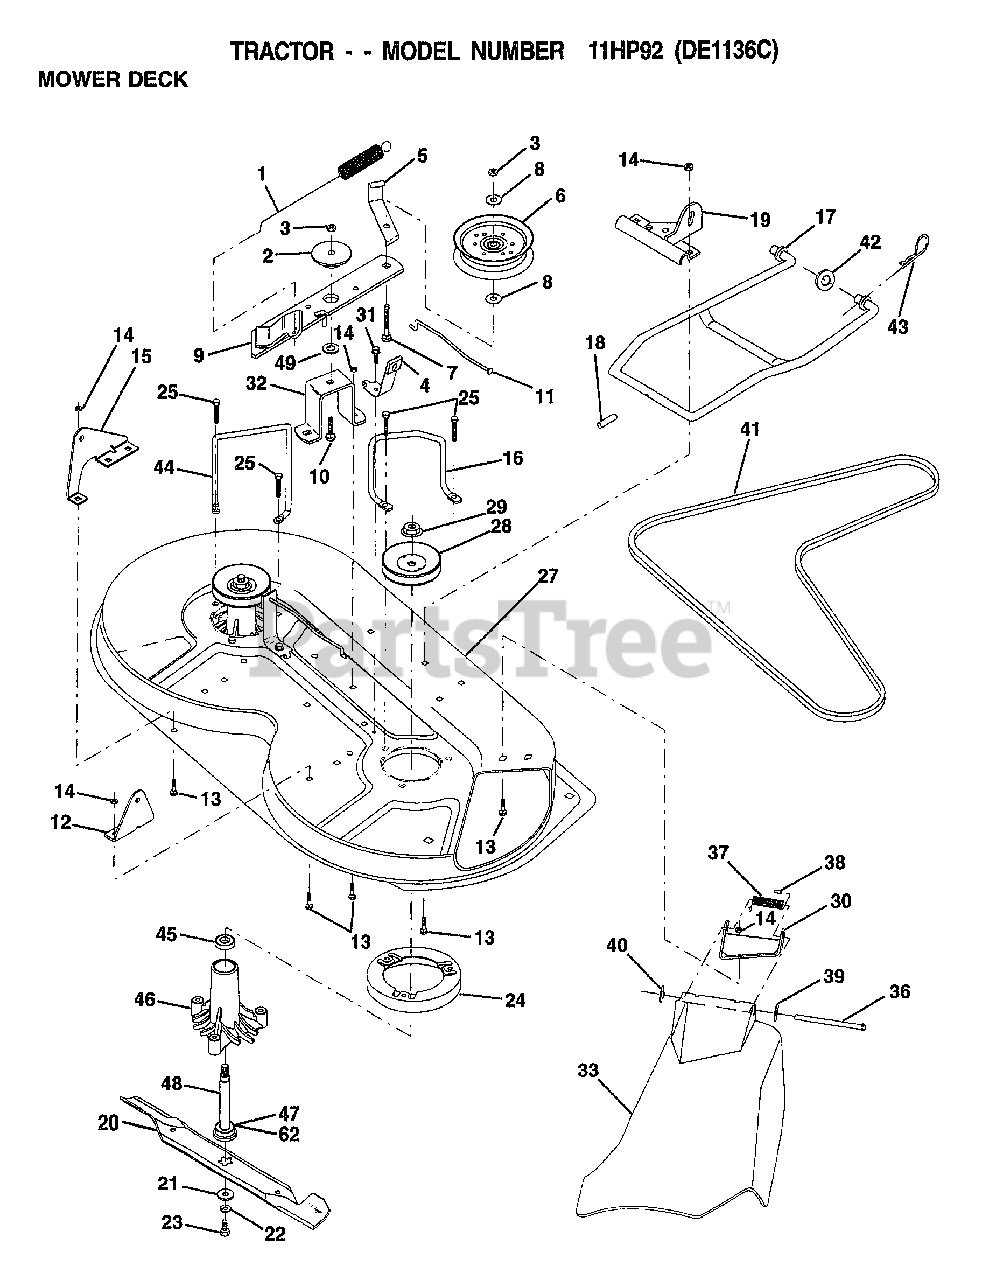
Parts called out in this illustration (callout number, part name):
1	SPRING CLUTCH MWR
2	SPACER.RETAINER.MOWER
4	BRAKE ASM
5	IDLER BELT GUIDE
6	PULLEY IDLER
7	BOLT
8	WASHER
10	BOLT.3/8-14X1.25
11	BRAKE ROD
12	"BRKT,LIFT REAR"
13	BOLT
15	"BRKT,LIFT REAR LH"
16	"KEEPER-BELT,RH"
17	MOWER LINK STAB
18	"PIN,GROOVE"
19	"BRKT,LINK STABILI"
20	"BLADE.36"" HIPERF"
21	WASHER.HARD.BLADE
23	BLADE BOLT
24	STRIPPER RND MWR
25	"SCREW-THD ROLL,WA"
27	"HOUSING-MOWER,36"""
28	PULLEY.MAND.36/46
31	SCREW LT
32	"SUPT,IDLER ARM"
33	SHIELD, DEFLECTOR
36	HINGE ROD
37	SPRING TORSION
38	CAP-SLEEVE LT
39	WASHER
40	NUT PUSH M
41	V-BELT.PRIM.78.5.
43	RETAINER.SPRING
44	KEEPER BELT LH
45	BEARING
46	HSG ASM MANDREL
47	BEARING.BALL
49	HARDENED WASHER
62	WASHER.FELT.
